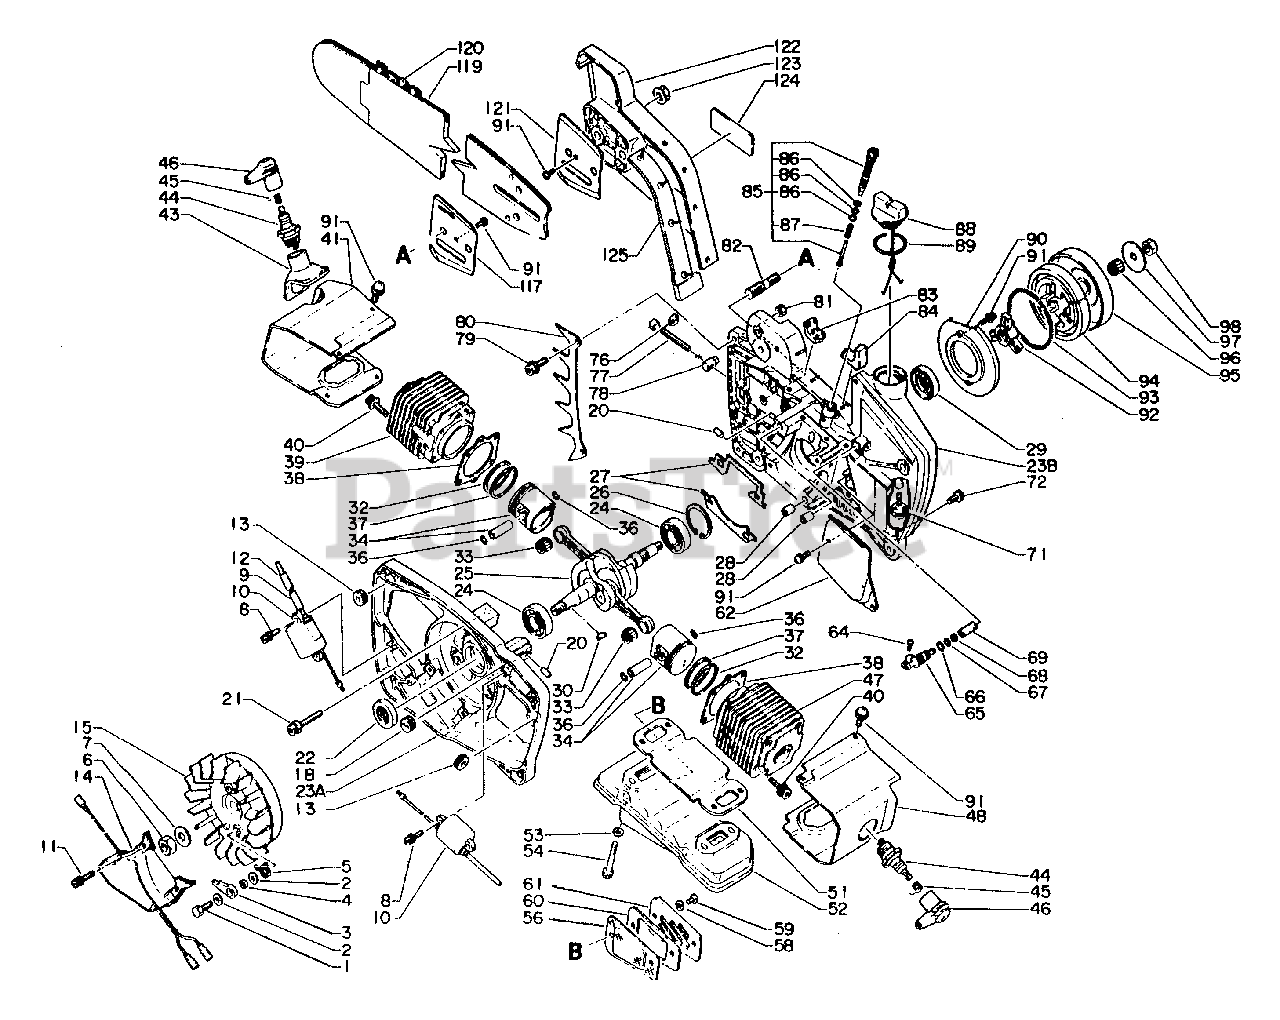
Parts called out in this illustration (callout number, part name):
1	BOLT - 5X16
2	WASHER - 5
3	PAWL, STARTER
5	SPRING, RETURN
7	LOCKWASHER
8	SCREW - 4X14
10	COIL, IGNITION
11	SCREW - 4X18
14	COIL, IGNITION
15	FLYWHEEL
20	PIN - LOCATING
21	SCREW - 5X35
22	SEAL, OIL
23	CRANKCASE KIT
23A	CRANKCASE KIT
23B	CRANKCASE KIT
24	BEARING, BALL - 6202
25	CRANKSHAFT ASSY
26	RING, RETAINING - 35
27	GASKET, CRANKCASE
28	PIN - LOCATING
29	SEAL, OIL
32	RING, PISTON
33	BEARING, NEEDLE
34	PISTON KIT
36	RING, RETAINING
37	RING, PISTON
38	GASKET, CYLINDER
39	CYLINDER - FRONT
40	SCREW - 5X20
41	COVER, CYLINDER - LEFT
43	SEAL, DUST
44	SPARK PLUG -- BPM-7A
45	TERMINAL, SPARK PLUG CAP
46	CAP, SPARK PLUG
47	CYLINDER - REAR
48	COVER, CYLINDER - RIGHT
51	GASKET, EXHAUST
52	MUFFLER
54	SCREW - 5X38
56	SCREEN, SPARK ARRESTOR
58	LOCKWASHER - 5
59	SCREW - 5X8
60	GASKET, EXHAUST
61	LID, MUFFLER
62	PLATE
64	SCREW - 3X8
65	CONNECTOR
66	O-RING - 7
67	O-RING - 6
68	CLIP - 5.5
69	PIPE - 3X5X90 -- BLACK
71	FILTER, OIL
72	SCREW - 5X10
77	SCREW, TENSIONER
78	TENSIONER, CHAIN
79	SCREW - 5X14
80	SPIKE
82	STUD, GUIDE BAR
85	AUTO-OILER ASSY
86	O-RING - 5
88	CAP ASSY
89	O-RING - 25
90	SEAL, DUST
91	SCREW - 4X10
92	HUB, CLUTCH
93	SPRING, CLUTCH
94	SHOE, CLUTCH
95	DRUM, CLUTCH
96	BEARING, NEEDLE
97	WASHER, CLUTCH
98	LOCKNUT
117	PLATE, GUIDE - INNER
119	GUIDE BAR - 50" (127cm)
120	SAW CHAIN - 72DP-72E
121	PLATE, GUIDE - OUTER
122	GUARD, SPROCKET
123	NUT - FLANGE
124	LABEL - ECHO
125	ISOLATER
